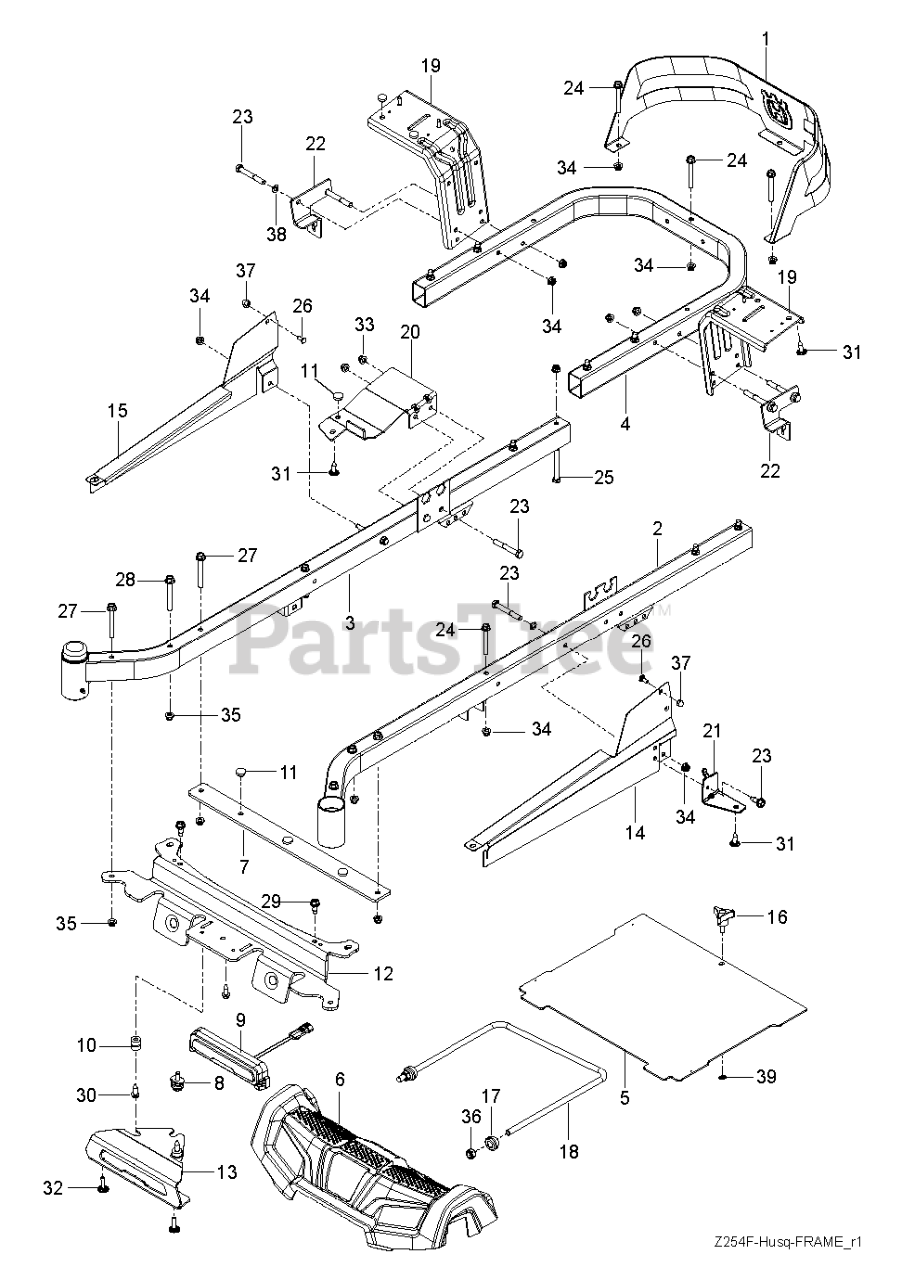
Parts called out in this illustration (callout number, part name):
1	GUARD.ENGINE.HUSQ.RZ.X498
2	FRAME.TUBE.RZ.MAIN.WELD.RH.ORG
3	FRAME.TUBE.RZ.MAIN.WELD.LH.ORG
4	TUBE.PNT.FRAME.RER.HUSQ.23".RZ
5	PLATE, FOOT W/DECALS RZ
6	COVER.FOOTREST.REFRESH.ASM
7	FOOTREST.PLATE.SUPPORT.X431
8	SCREW.ADJ.ISOLATOR.BOLT.ASSY
9	LIGHT.ZTR.LED.ASM
10	GROMMET.RUBBER.PUSHIN
11	GROMMET.BUMPER
12	CROSS.PNT.MEMBER.BLK
13	BRACKET.SKIDPLTE.LED.RFRSHX417
14	COVER.RAIL.RH.RZ.X668
15	COVER.RAIL.LH.RZ.X668
16	KNOB W/STUD
17	BUSHING SPHERICAL SUSP. FRONT
18	LINK, FRONT SUSP.
19	FENDER.SUPPORT.PNT.X431
20	SUPPORT.PNT.RH.CONSOLE.FRONT
21	SUPPORT.PNT.LH.CONSOLE.FRONT
22	BRKT ROD.BYPASS.EZT.X431
23	BOLT.FIN HEX 5/16-18UNC X2 1/4
24	BOLT HEX
25	BOLT.HEX.FIN.3/8-16 X 3.GR5
26	BOLT.CARRIAGE.5/16-18.7/16
27	HHFS 3/8-16 X 3 GRD 5 ZD
28	BOLT SHOULDER,FLANGED,3/8-16X3
29	BOLT.5/16-18.THRD.ROLL.SHOULDR
30	BOLT.5/16-18X1.25
31	SCREW.#10 X 0.750.BOS
32	SCREW.#10 X 0.500
33	NUT LOCK HEX FLANGE 5/16-18
34	5/16-18 NYLOC FLANGE NUT
35	NUT 3/8-16 HEX FLG NYLOC ZD
36	7/16-14 HEX NUT W/NYL RING ZD
37	NUT ACORN,FLANGED,5/16-18
38	WASHER
39	WASHER 5/16"
